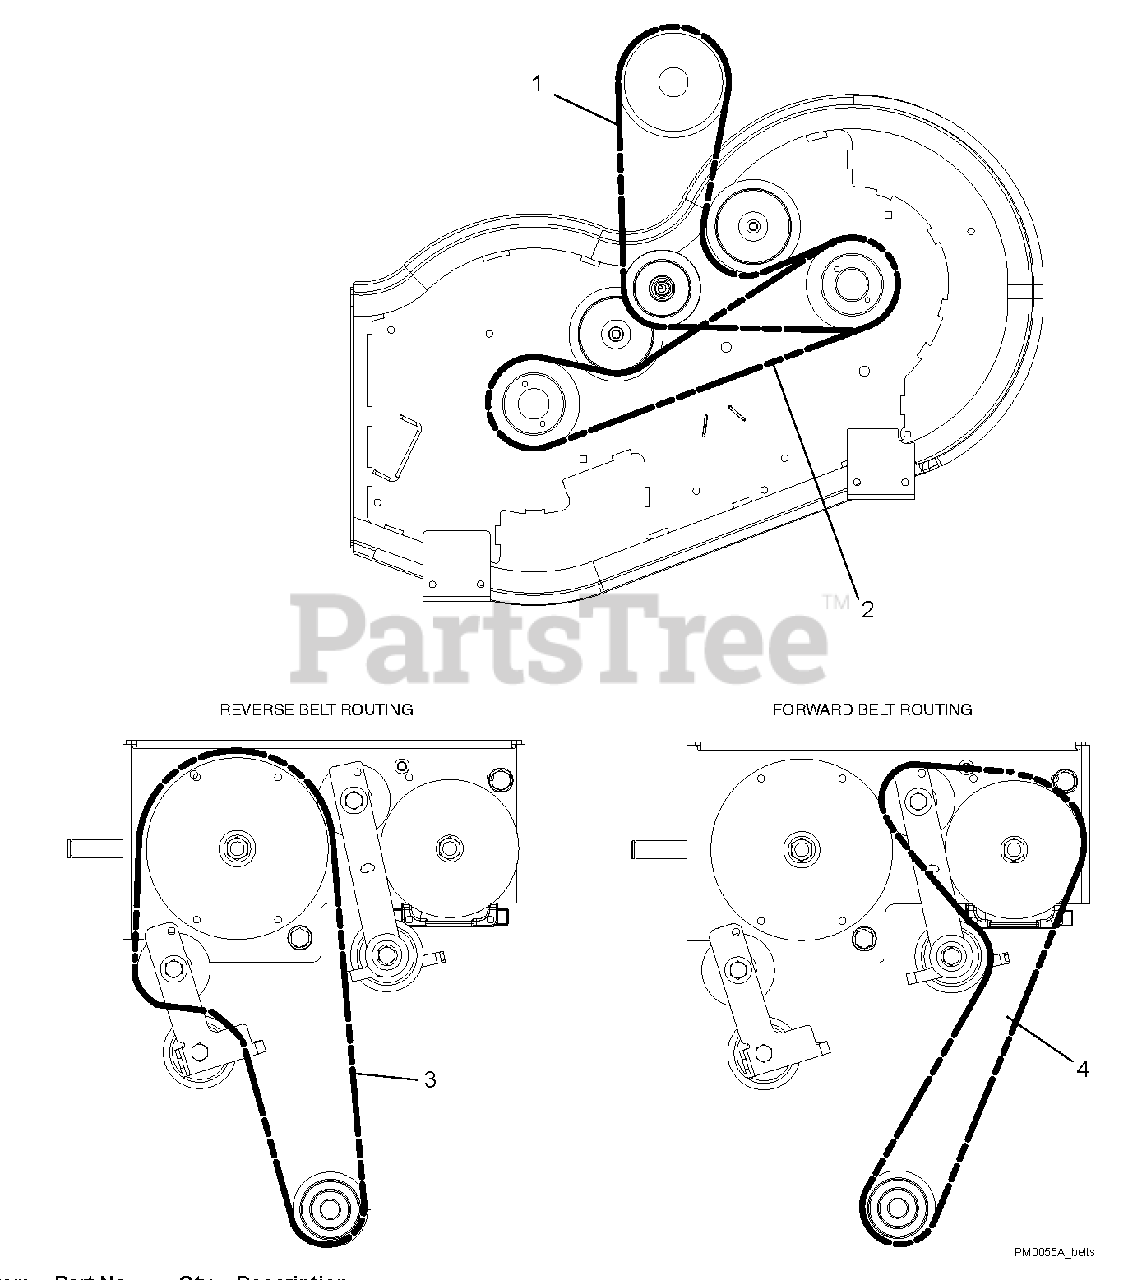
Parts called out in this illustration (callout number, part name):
1	Belt, HA 56.95 Wrapped
2	Belt, HA 51.20 Wrapped
3	Belt, 3L Clutching Cover
4	Belt, 3L Clutching Cover
